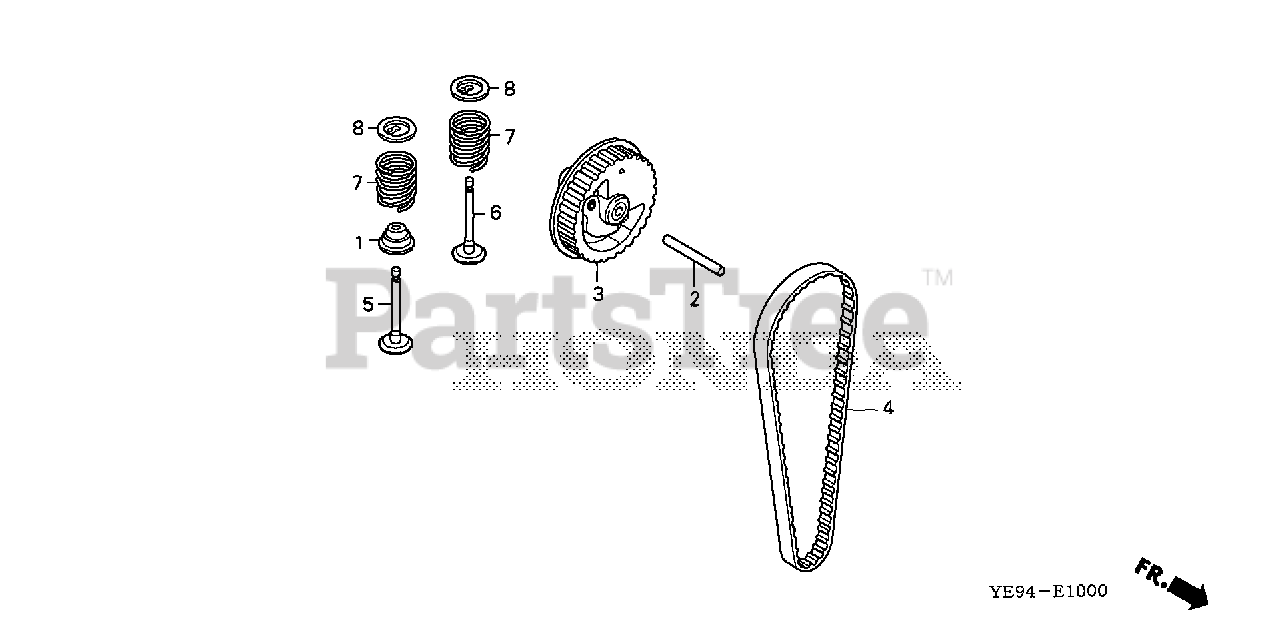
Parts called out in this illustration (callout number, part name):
1	SEAL, VALVE STEM
2	ROLLER (4X29.8)
3	PULLEY, CAMSHAFT
4	BELT, TIMING (71ZU5 G-310)
5	VALVE, IN. (EI)
6	VALVE, EX. (EE)
7	SPRING, VALVE
8	RETAINER, VALVE SPRING
